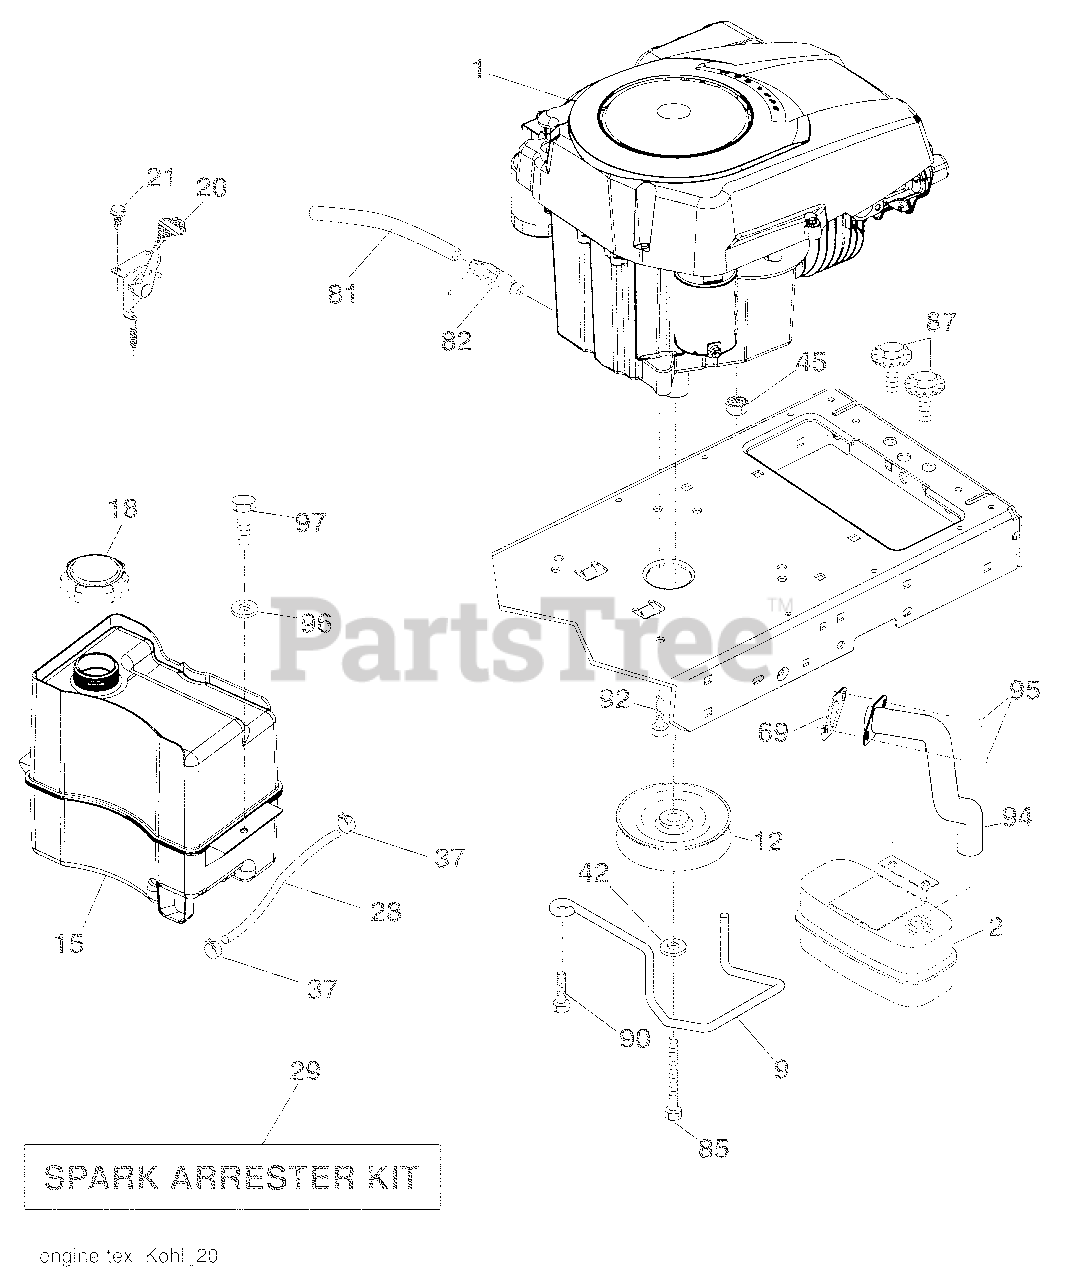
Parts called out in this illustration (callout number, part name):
9	Keeper Belt Engine
12	Pulley Engine
15	Tank Fuel
18	Cap Asm
20	Control Throttle
21	Screw # 10 x 0.750
28	Fuel Line
29	Spark Arrester Kit
37	Clamp Hose
42	Washer Lock 7/16
45	Nut Keps Hex 1/4-20 unc
81	Tube Drain Oil Easy
82	Valve Oil Drain
85	Bolt Hex 7/16-20 x 4 x Gr. 5-1.5 Thr
87	Bolt 5/16-18 unc x 3/4 w/Sems
90	Screw 3/8-16 x 1
92	Screw 3/8-16 x 1
94	Tube Exhaust
95	Screw Socket Hd. 5/16-18 x .75
96	Washer 9/32 x 7/8 x 16 Ga.
97	Screw 1/4-20 x 3/4
